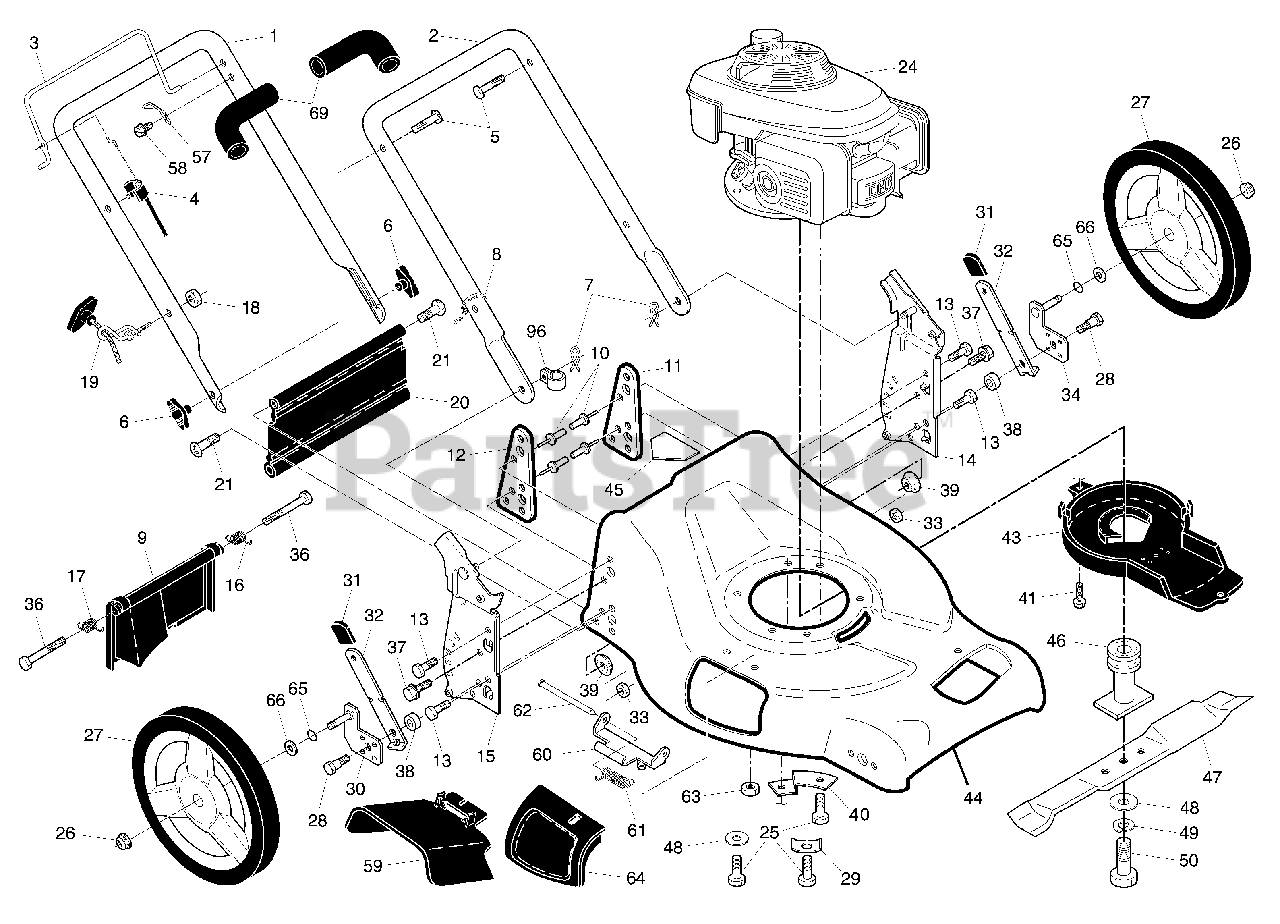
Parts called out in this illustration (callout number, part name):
1	Upper Handle, with Foam Grip
2	Lower Handle
3	Control Bar
4	Engine Zone Control Cable
5	Handle Bolt
6	Handle Knob
7	Hairpin Cotter
8	Wire Tie
9	Rear Door Assembly
11	Support Bracket, LH
12	Support Bracket, RH
13	Screw 1/4-20 x 5/8
14	Handle Bracket Assembly, LH
15	Handle Bracket Assembly, RH
16	Spring, Rear Door, LH
17	Spring, Rear Door, RH
18	Keps Locknut 1/4-20
19	Rope Guide
20	Rear Skirt
21	Screw, Hinge 1/4-20 x 1/2
25	Hex Head Thread Rolling Screw 3/8-16 x 1-1/8
26	Hex Flange Nut
27	Wheel & Tire Assembly, Rear, 12"
28	Shoulder Bolt 5/16-18 x .33
29	Washer, Engine, Zinc-Plated
30	Axle Arm Assembly, Rear, RH
31	Selector Knob
32	Selector Spring
33	Nut, Hex 5/16-18
34	Axle Arm Assembly, Rear, LH
37	Thread Cutting Screw w/Sems 5/16-18 x 3/4
39	Nut, Hex, Flangelock 5/16-18
40	Mounting Bracket, Debris Shield
43	Debris Shield
44	Kit, Lawn Mower Housing
45	Danger Decal
46	Blade Adapter / Pulley
47	Blade, 21"
48	Hardened Washer
49	Helical Washer 3/8-24 x 1-3/8 Grade 8
50	Hex Head Machine Screw 3/8-24 x 1-3/8 Grade 8
57	Upstop Bracket
59	Discharge Defl ector
60	Hinge Bracket
63	Nut, Hex
64	Mulcher Door
66	Washer, Flat 1/2
69	Grip, Foam
96	Clip, Cable
